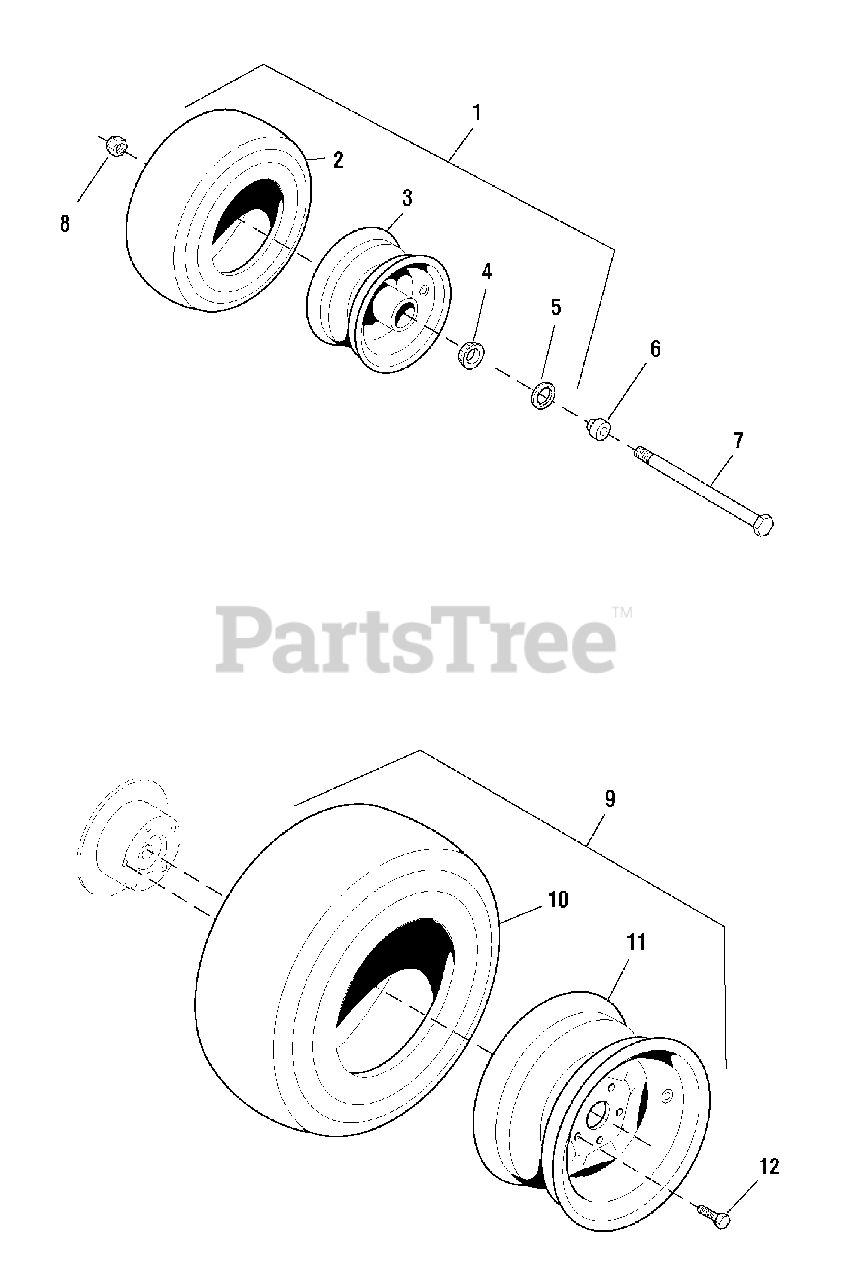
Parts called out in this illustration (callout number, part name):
1	WHEEL & TIRE ASSEMBLY, Front, 13 x 5.0 x 6, Complete
2	TIRE, Front, 13 x 5.0 x 6
3	WHEEL ASSEMBLY, Front, for 13 x 5.0 x 6 Tires, Complete
4	BEARING, TAPERED CONE
5	SEAL, GREASE
6	ADAPTER, Caster Wheel
7	CAPSCREW, Hex Hd, 1-2/13 x 7-1/2
8	NUT, Hex, Nylon Lock, 1-2/13
9	WHEEL & TIRE ASSEMBLY, Rear, 23 x 10.5 x 12, Complete
10	TIRE, Rear, 23 x 10.5 x 12
11	WHEEL ASSEMBLY, Rear, 21 x 8.5
12	WHEEL LUG, 1/2 x 1-5/8
